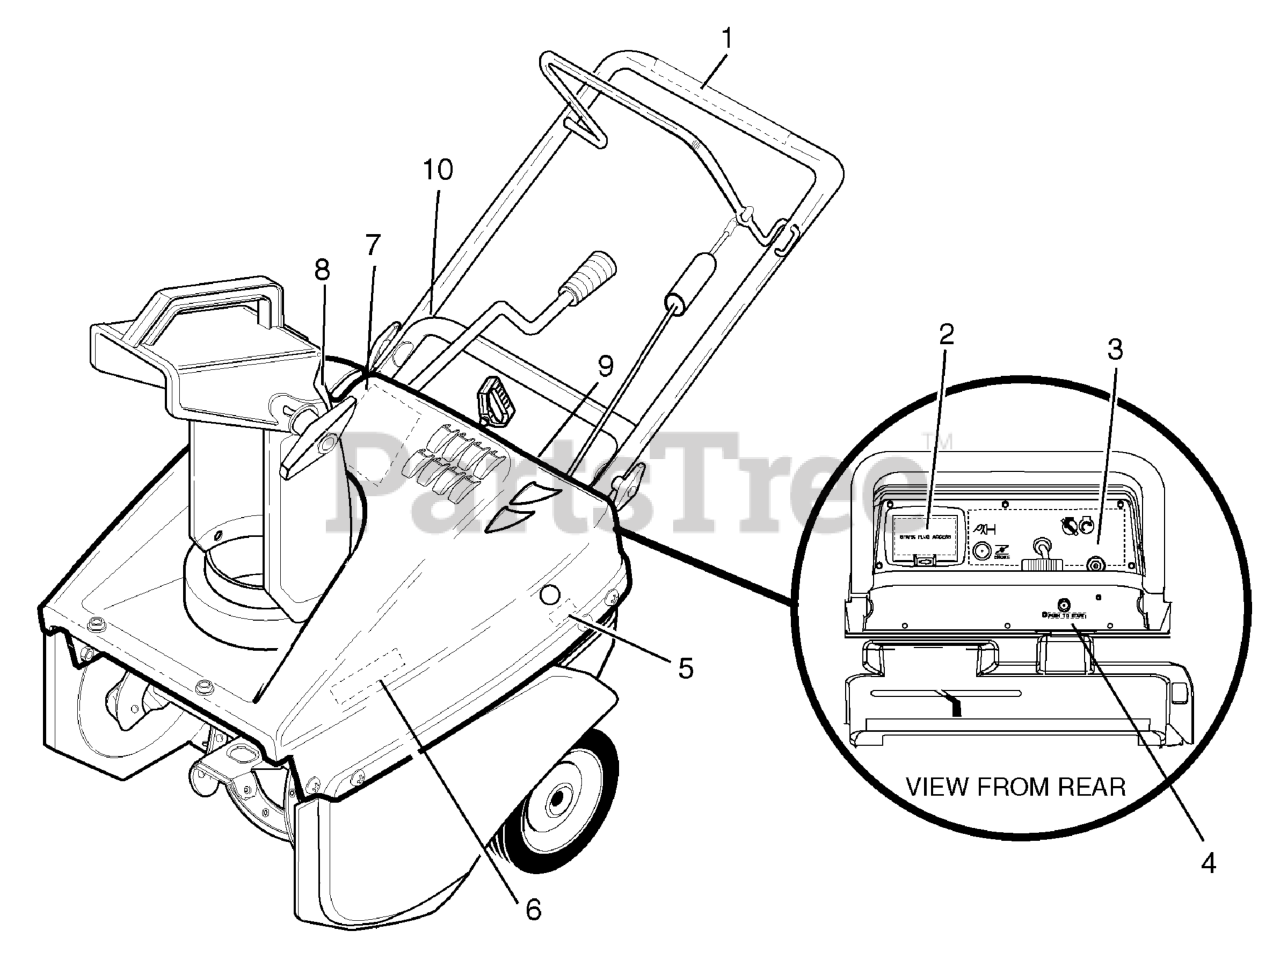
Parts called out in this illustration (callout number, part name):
1	Decal, Auger Control Bar
2	Decal, Spark Plug Access
3	Dash 21" French/English
4	Decal, Push To Start
5	Danger, Muffler
6	Decal, Auger French/English
7	Decal, Murray 525/21
8	Decal, Danger Auger Chute French/English
9	Decal, Access Cover Warning
10	Decal, Handle Protector
